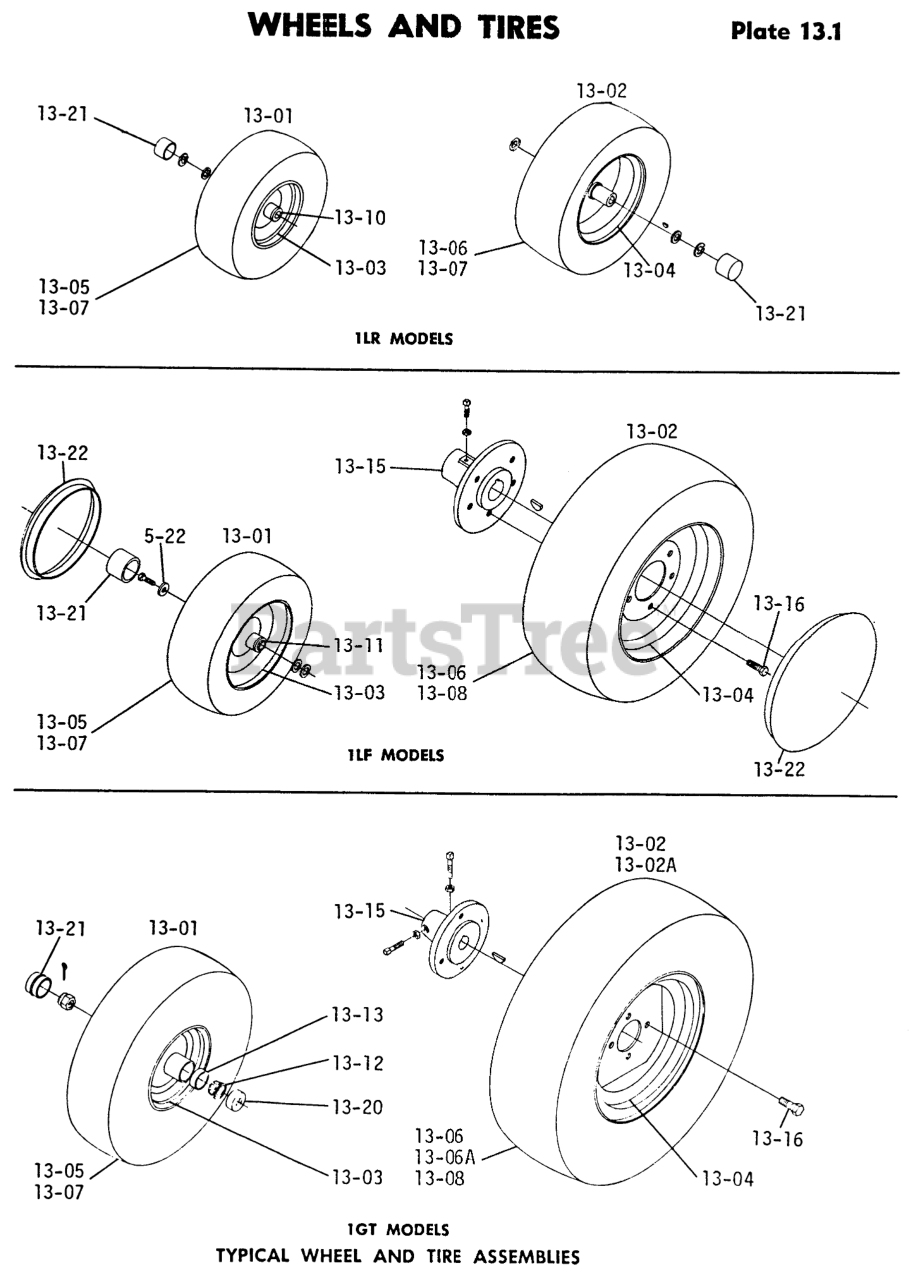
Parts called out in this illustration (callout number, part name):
13-01	Wheel and Tire
13-02	Rear Wheel
13-02	Wheel and Tire Complete
13-02A	Opt. Rr. Wheel Assy. (Cleat Tire)
13-04	Wheel
13-04	WOODRUFF KEY
13-04	WASHER
13-05	TIRE
13-06A	Rear Tire 27 x 8.50-15 Cleat
13-10	BUSHING-FLANGED
13-10	E-RING
13-10	WASHER
13-11	Bolt 3/8-16 x 7/8
13-11	WASHER
13-11	WASHER-SHIM
13-13	Cotter Pin 1/8 x 1/3
13-15	3/8-16 Jam Nut
13-15	KEY-WOODRUFF
13-16	BOLT-LUG, WHEEL
13-20	Seal
13-21	HUB CAP
13-22	Disc 8" Wheel
13-22	Disc 12" Wheel
